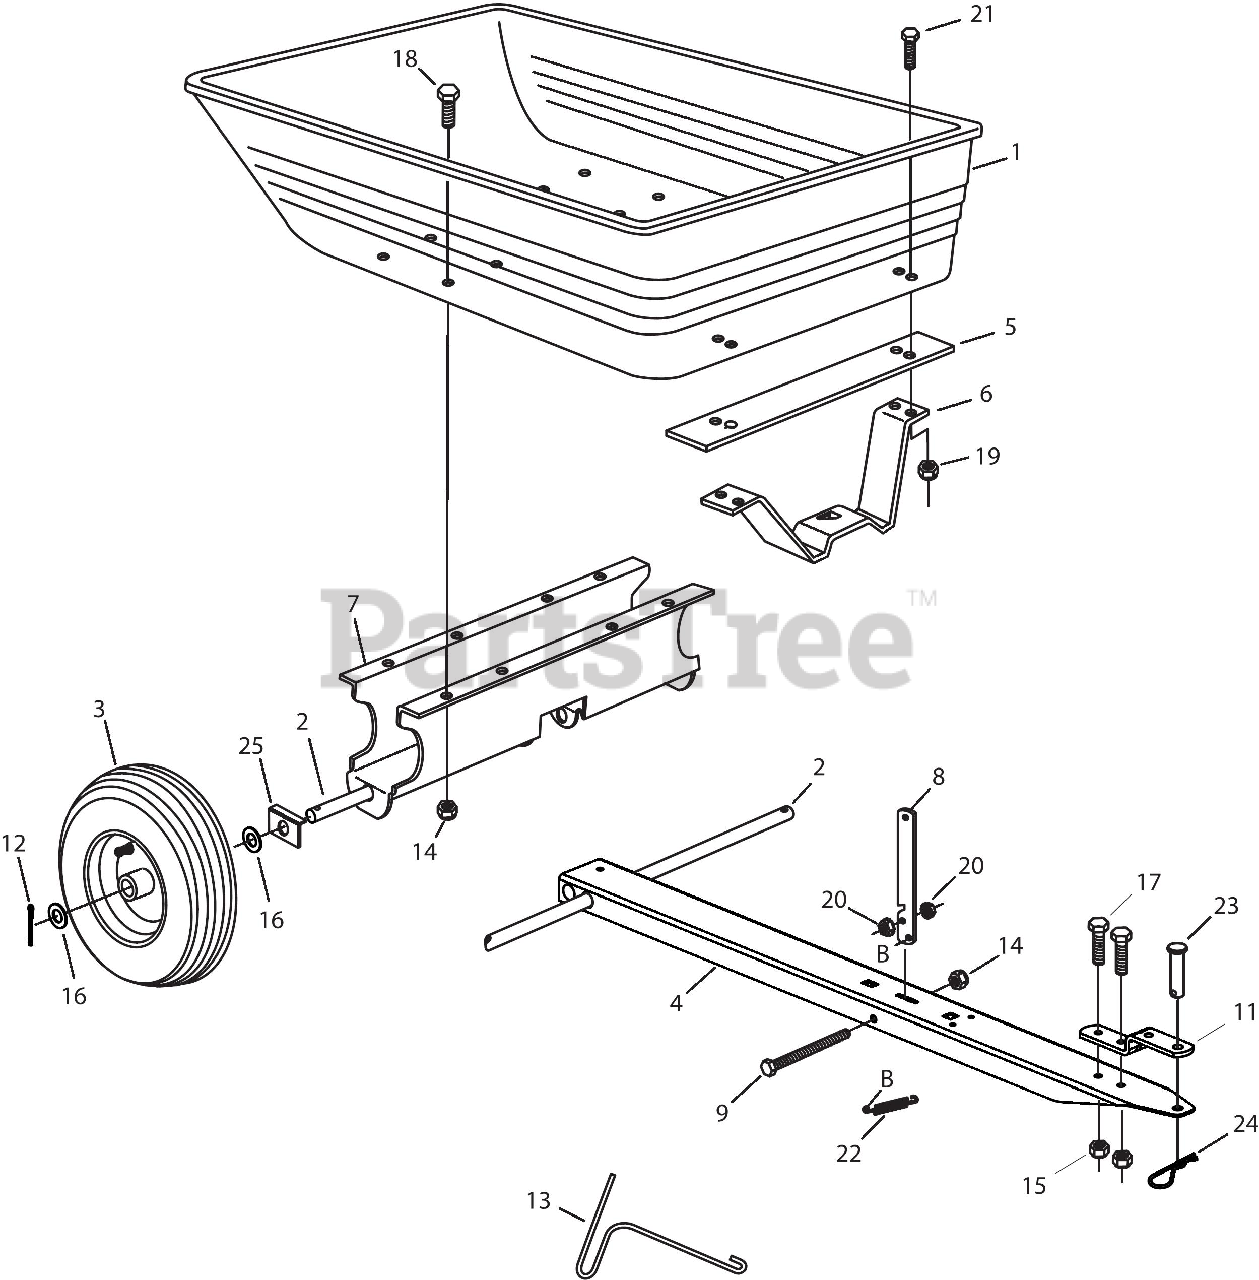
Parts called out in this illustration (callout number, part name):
1	Poly Tray
3	Wheel Assembly
4	Tounge Draw Bar
5	Latch Stand Plate
7	Wheel Support
8	Lever-Latch Lock
9	Hex Bolt 5/16 X 3-3/4
11	Bracket-Hitch
12	Cotter Pin-1/8 D
13	Puller-Spring
14	Hex Nut Ins
15	Hex Nut Ins L-3/
16	Washer-Pivot 21/32
17	Hex Screw 3/8-16
18	Hex Bolt 5/16-18 X 3/4
19	Nut-Nylon Lk 1/4
20	Hex Nut
21	Hex Screw 1/4-20
22	Extension Spring
24	Hairpin Cotter 1/8
25	Axle Keeper
769-11326	Owners Manual
